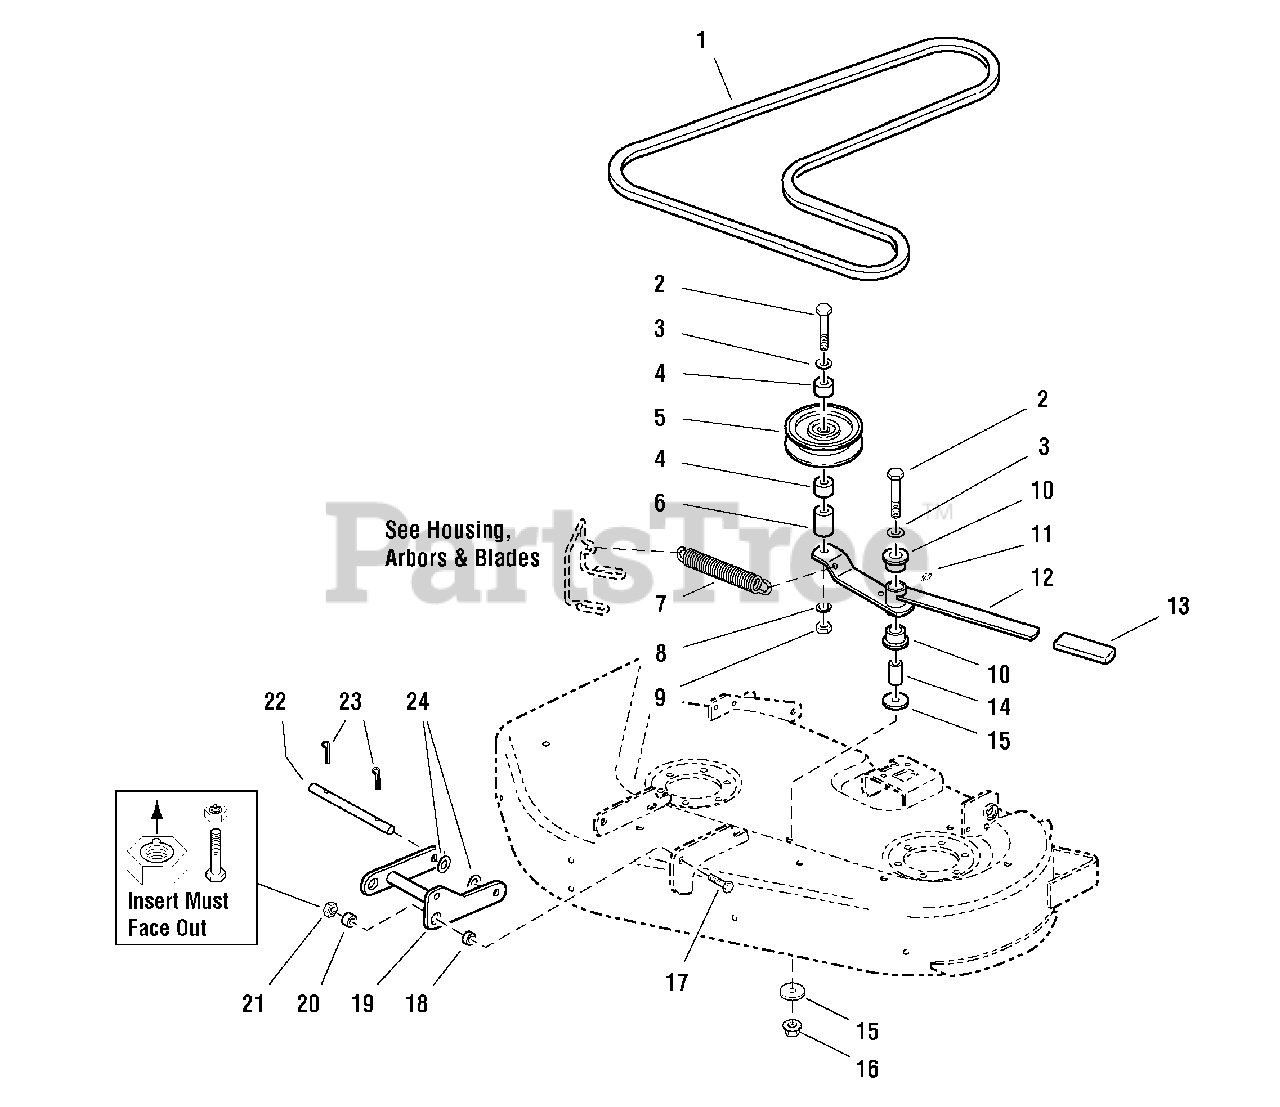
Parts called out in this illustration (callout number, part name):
2	CAPSCREW, Hex Head, 3/8-16 x 2-3/4
3	WASHER, 3/8
5	PULLEY, Idler
7	SPRING, Extension
8	LOCKWASHER, 3/8
9	NUT, Hex, 3/8-16
11	FITTING, Lube
12	LEVER & ARM ASSEMBLY, Complete (Includes Ref. No. 10 & 11)
13	GRIP
15	WASHER, 3/8
16	NUT, Hex Serrated Flange, 3/8-16
17	CAPSCREW, Hex Head, 3/8-16 x 1-1/2
21	NUT, Hex Lock, Aluminum Insert, 3/8-16
23	PIN, Cotter
24	WASHER, 1/2
